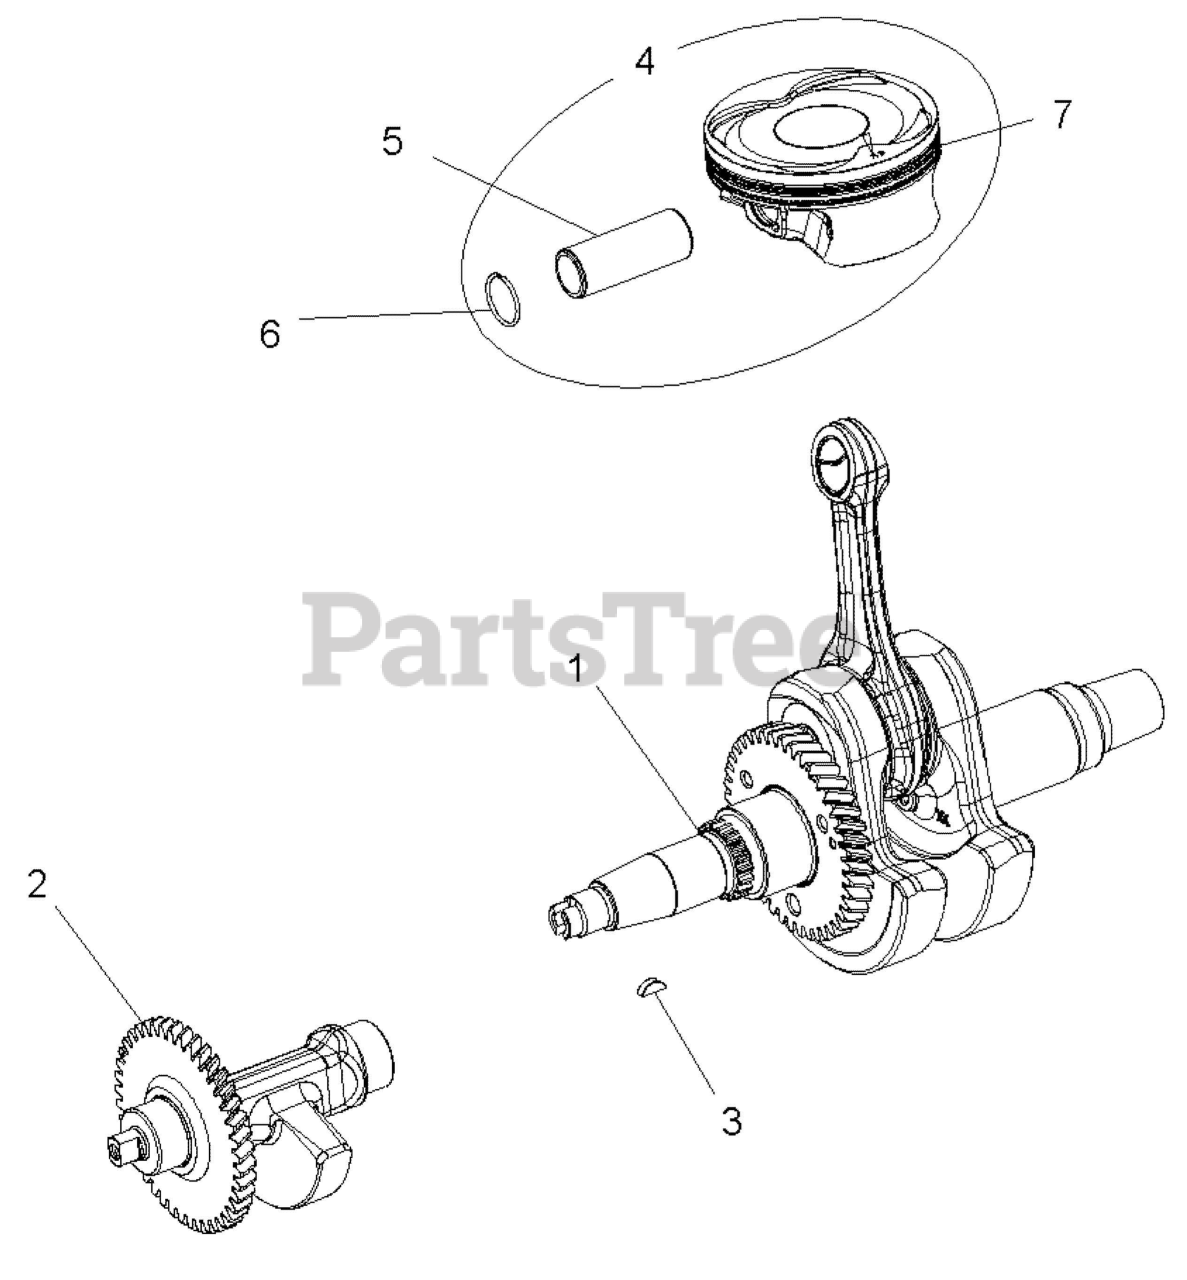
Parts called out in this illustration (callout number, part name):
1	ASM, CRANKSHAFT
2	ASM-BALANCE SHAFT
3	KEY,WOODRUFF
4	KIT-PISTON 99MM
5	PIN-PISTON,22X12.8X56.6MM
6	C-CLIP,RND (2)
7	KIT-RING,STD
